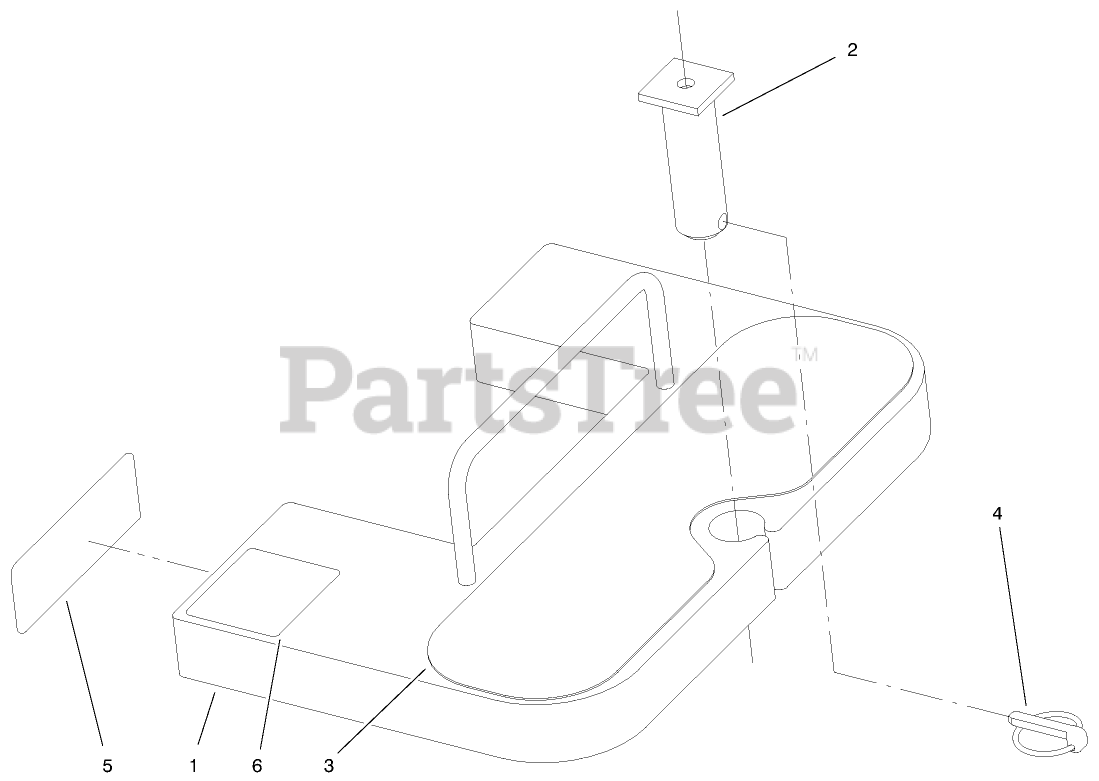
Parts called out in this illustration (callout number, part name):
1	Counterweight
3	TREAD-FOOT
4	PIN-LYNCH
5	Decal-CE
6	DECAL
